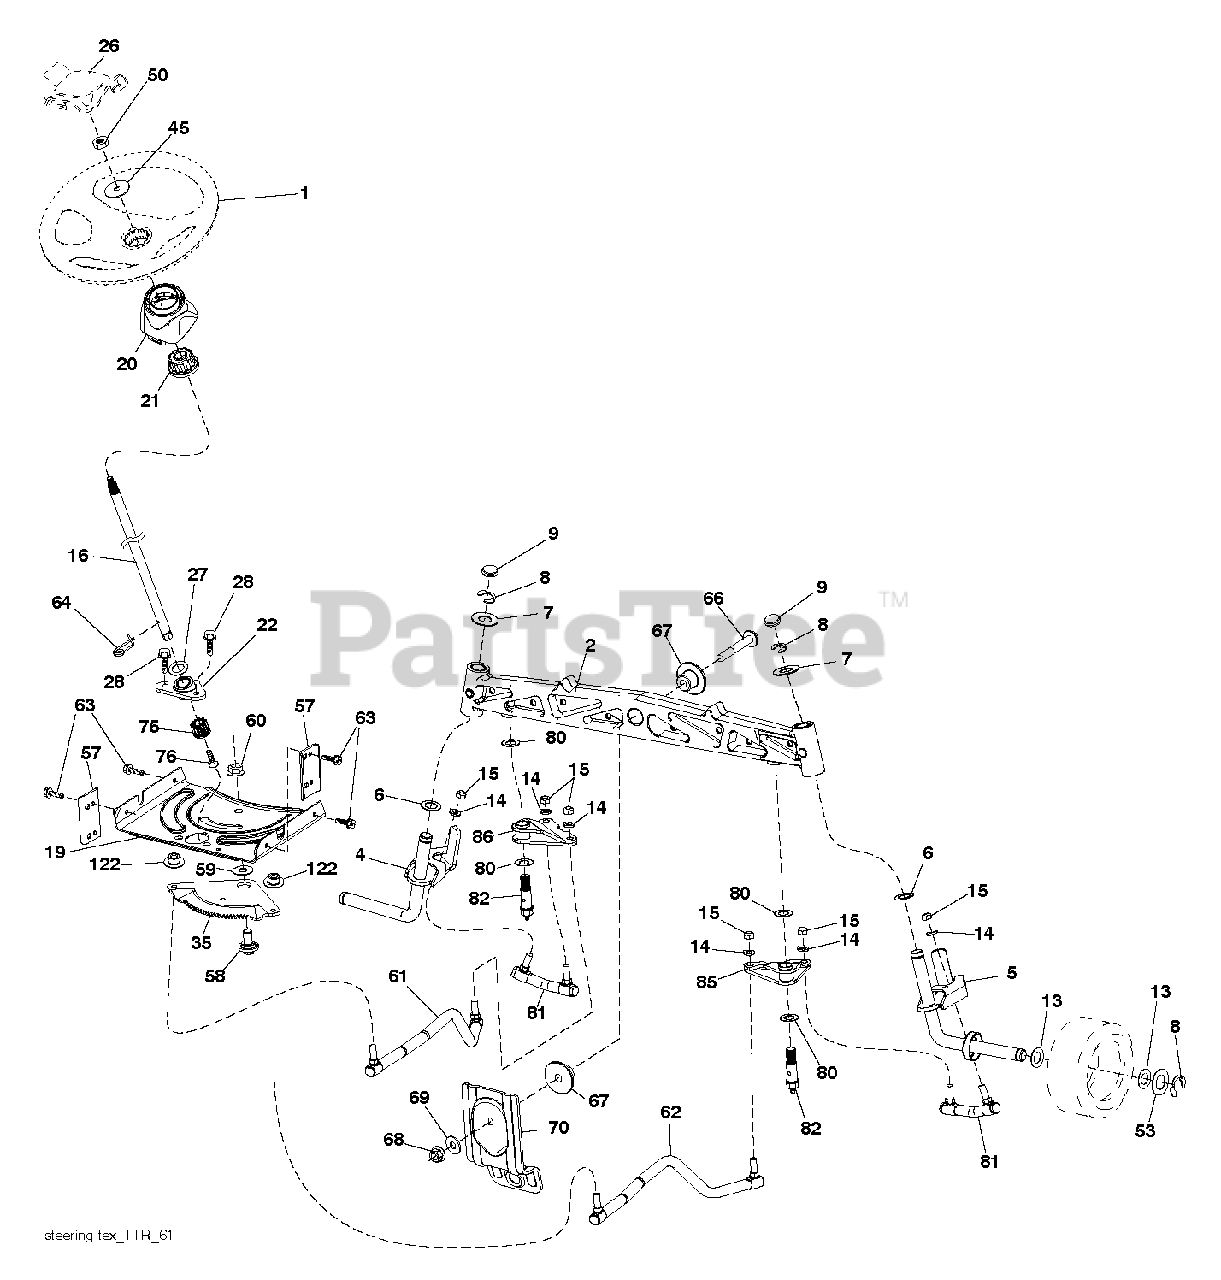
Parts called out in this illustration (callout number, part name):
1	WHEEL.STEERING.HARD.RIM.BLAC
2	RP SUBASM.AXLE.CAST.N
4	SPINDLE WELDMENT.SPIN
5	SPINDLE WELDMENT.SPIN
8	RING CLIP
9	CAP.SPINDLE.BLACK
14	WASHER, LOCK 3/8
15	NUT CROWNLOCK 3/8-24
19	PLATE.STEER.DDL.NLT/NG
20	BOOT.STRNG.PREDATOR.YT/GT.428
26	INSERT, WHEEL STEERING
27	WASHER LT
28	SCREW, 3/8-16X3/4
35	GEAR GEAR.SECTOR.TEX.
45	WASHER.3/8ID.2-3/8OD.12GA.PLTD
50	NUT LOCK FLG 3/8-16 UNC
53	WASHER.HARDENED
57	BRACKET.UPSTOP.TEX
58	BOLT.SHOULDER.SECTOR.P
59	WASHER.THURST.SECTOR.S
60	NUT FLANGE LOCK 5/8-11
61	LINK SUBASM.LINK.DRAG
62	TUBE TUBE
63	SCREW
64	RETAINER.CLIP.SPRING.S
66	BOLT HEX FGHD 7/16-14 X 3 SERR
67	BUSHING.PM.FRONT AXLE
68	NUT.LOCK.FLANGE.7/16
69	WASHER.1.5X.505X.118
70	Deck Suspension Bracket, Front RR
76	Screw Head Socket Lrvb
80	THRUST WASHER
81	LINK SUBASM.LINK.CROS
82	SUBASM;PIVOT;BOLT;NZTR
85	PIVOT SUBASM.PIVOT.RH
86	PIVOT SUBASM.PIVOT.LH
122	CAP.GEAR.SECTOR.TEX
